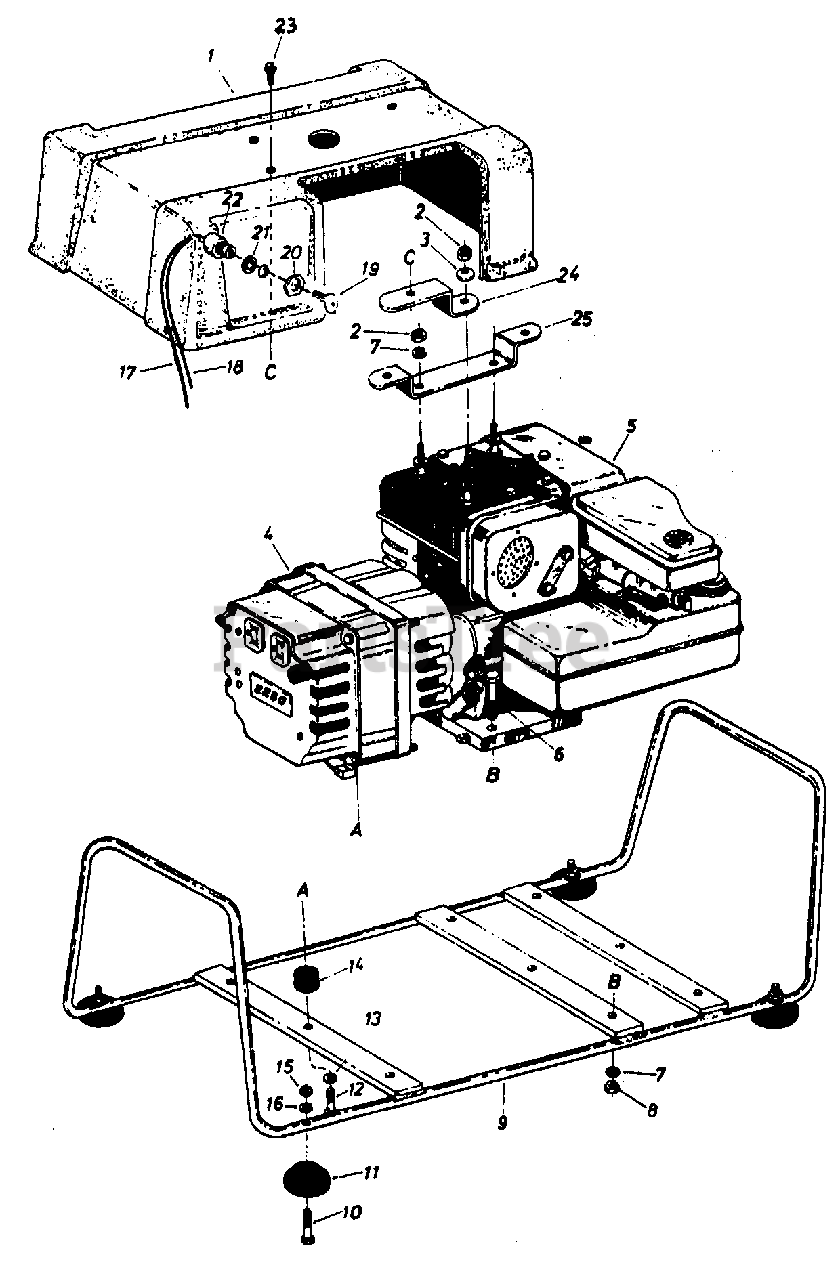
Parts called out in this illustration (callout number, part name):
2	Hex Nut 5/16-18 Thd.*
3	BellevilleWash. .345 I.D. x .88 O.D.
4	Generator
5	Engine
6	Hex Bolt 5/16-18 x 1.75" Lg.*
7	L.-Wash. 5/16" I.D.*
8	Hex Nut 5/16-18 Thd.*
9	Carriage Ass'y.
10	Truss Mach. Scr. 1/4-20 x 1.75" Lg.*
11	Rubber Bumper
12	Hex Sems Bolt 5/16-18 x .62" Lg.
13	L.-Wash. 5/16" I.D.
14	Rubber Bumper
15	Hex Nut 1/4-20 Thd . *
16	L.-Wash. 1/4" I.D.
17	Electric Wire (Ground on Gen.)
18	Electric Wire (To Engine)
19	Ignition Key
22	Ignition - Safety Switch
23	Hex Wash Hd. TT-Tapp Scr. 5/16-18 x .50" Lg.
24	Cover Bracket
25	Cover Bracket
